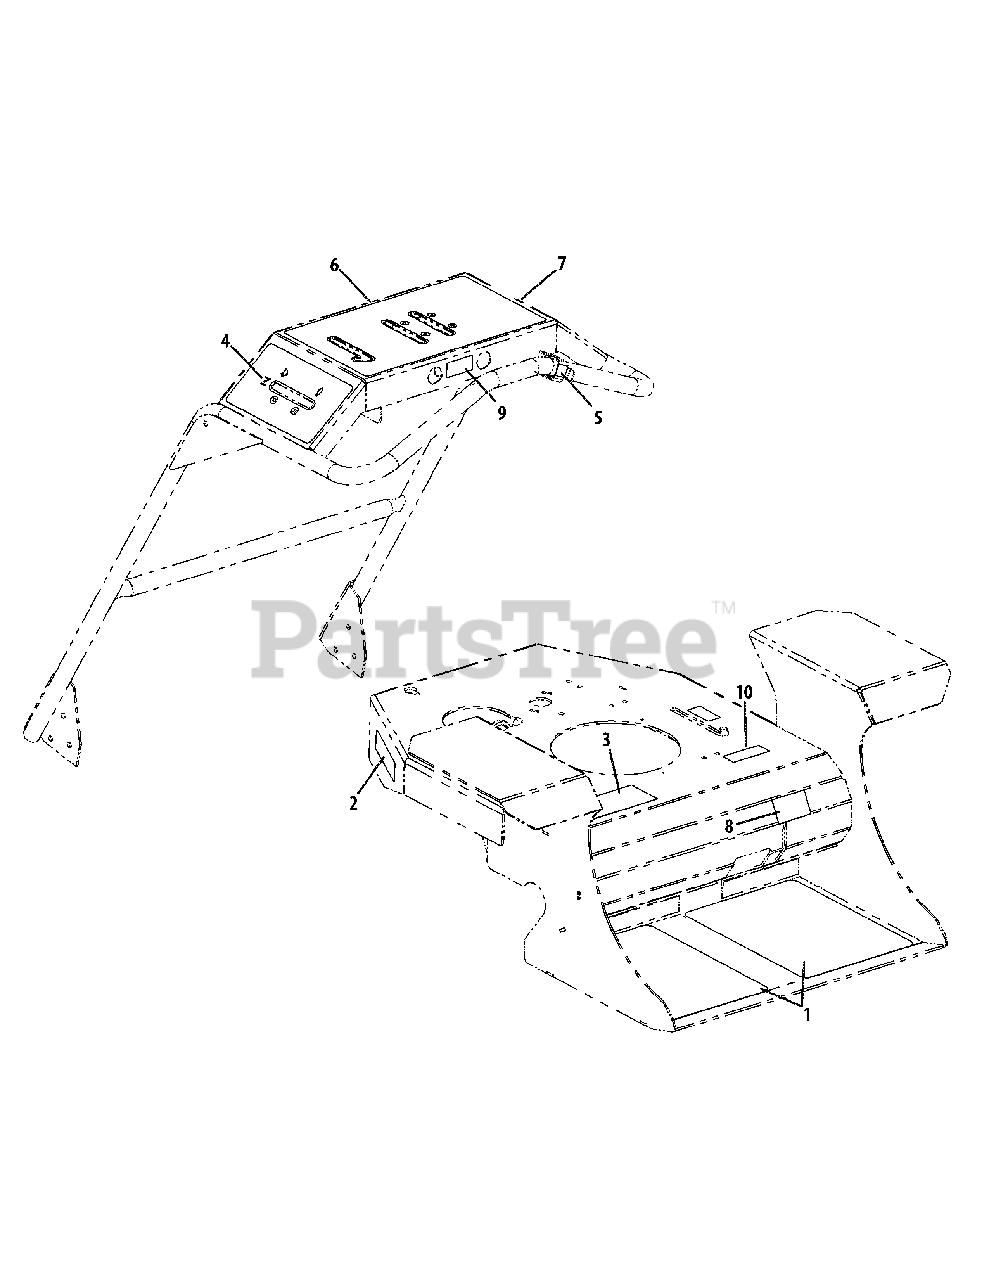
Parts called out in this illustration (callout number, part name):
1	Foot pad-Abrasive
2	Decal, Cub Cadet Commercial
3	Decal, Cub Cadet Commercial, Small
4	Decal, Throttle
5	Decal, Speed Control
6	Decal, Operator Panel
7	Decal, CCC
8	Decal, Parking Brake
9	Decal, Fwd/Rev
10	Decal, Warning Spark
